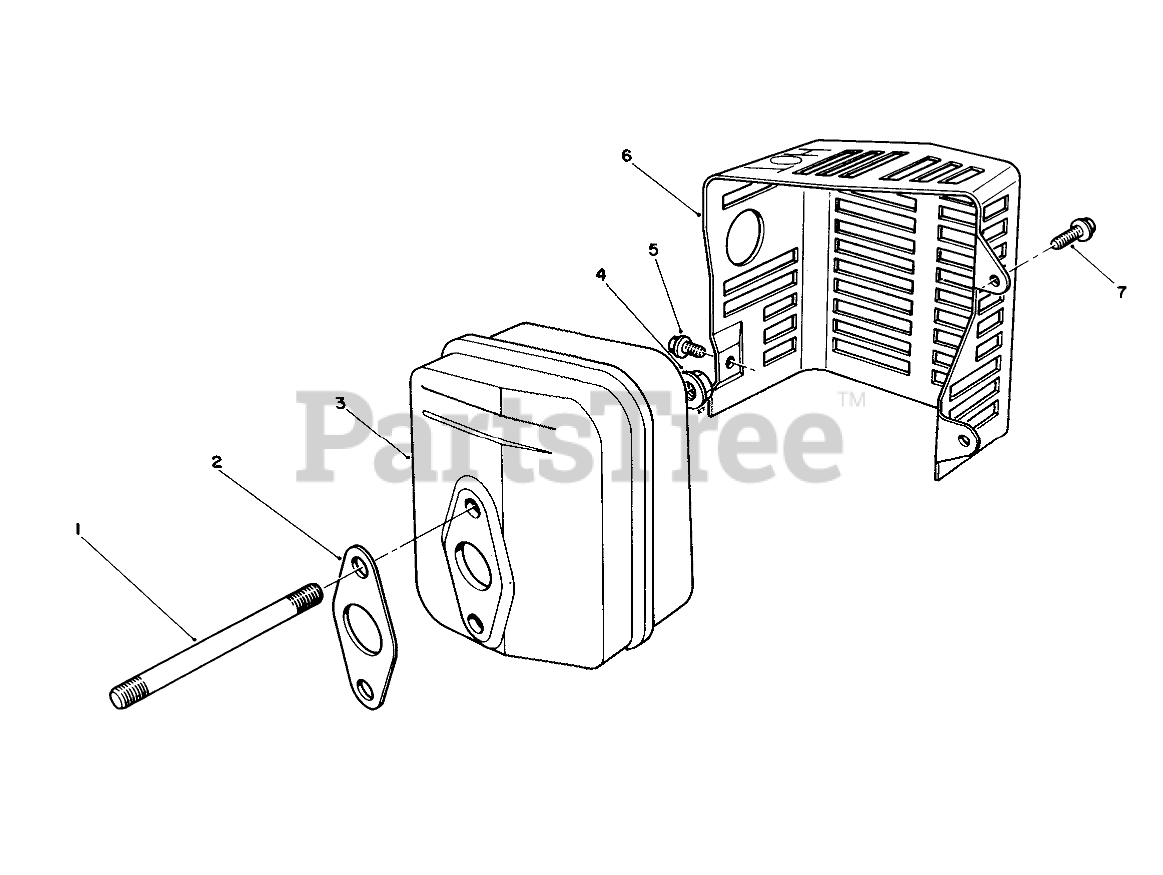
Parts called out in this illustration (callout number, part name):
2	GASKET
3	MUFFLER
5	SCREW
6	COVER
